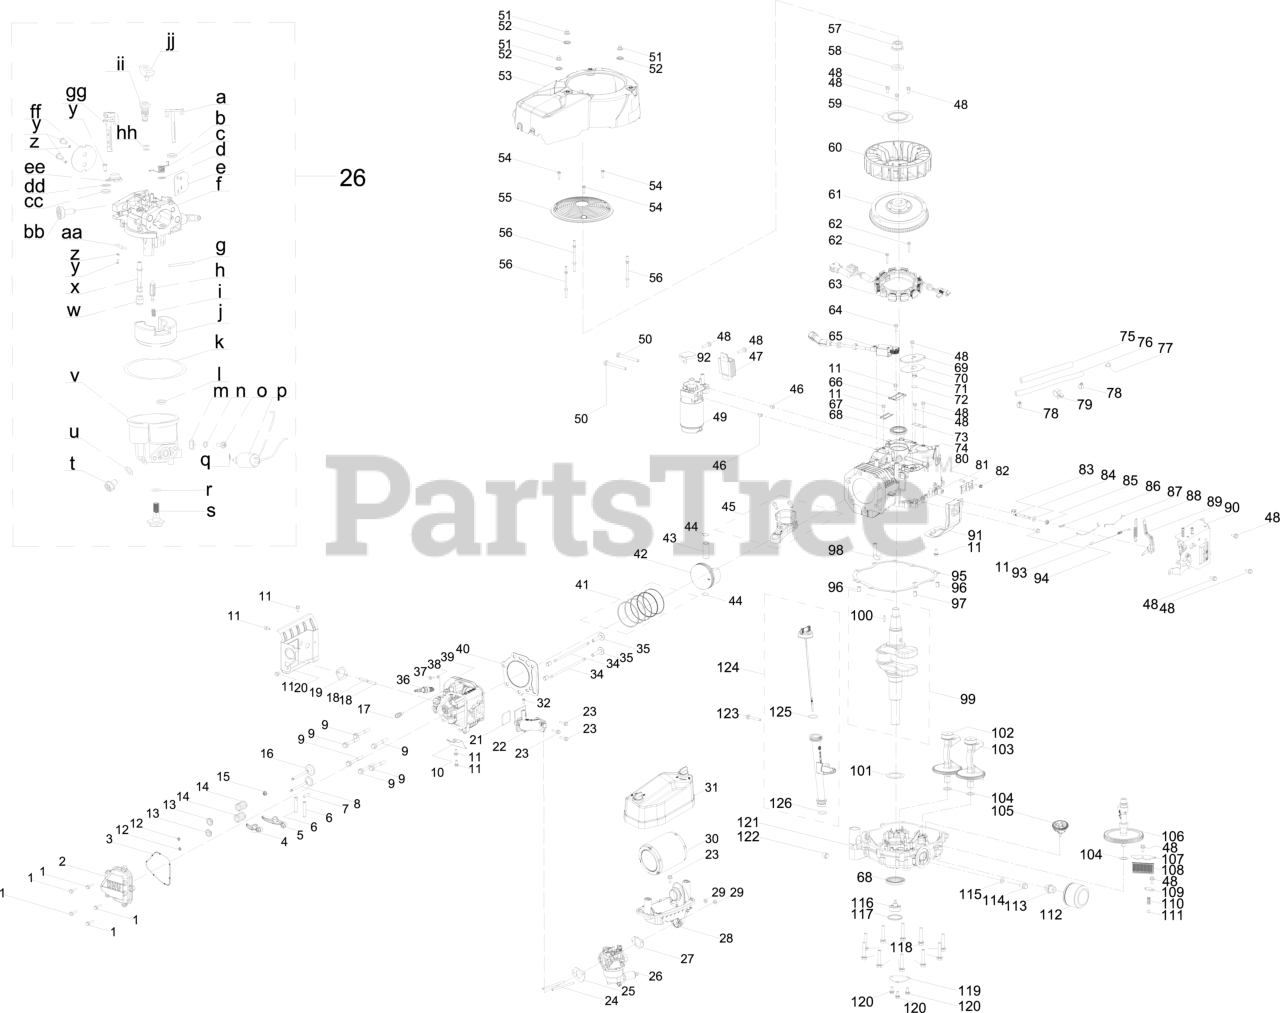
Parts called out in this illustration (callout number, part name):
1	BOLT M6-1 x 25 GR8.8
2	VALVE COVER
3	VALVE COVER GASKET
4	ROCKER ARM (INTAKE)
5	ROCKER ARM (EXHAUST)
6	ROCKER ARM SHAFT
7	CAMSHAFT PIN
8	EXHAUST VALVE
9	BOLT M10-1.25 x 70
11	BOLT M6-1 x 12 GR8.8
12	VALVE CAP
13	VALVE SPRING SEAT
14	VALVE SPRING
15	INTAKE VALVE SEAL
16	INTAKE VALVE
19	EXHAUST GASKET
20	SHROUD - LEFT SIDE
21	INTAKE PIPE RING
22	INTAKE PIPE
23	BOLT M6 x 22
24	STUD M6-1.00 x 92
25	INTAKE GASKET
27	AIR FLTER GASKET
28	INTAKE MANIFOLD
30	AIR FILTER W/PREFILTER
30	Cub Cadet AIR FILTER/PRE-FILTER
30	Genuine Factory Parts AIR FILTER
30	Troy-Bilt AIR FILTER (05066)
31	AIR FILTER COVER
32	SELF TAPPING SCREW 4.8 x 16
34	SINGLE PUSH ROD
36	SPARK PLUG (F6RTC/RN11YC/BPR6ES)
37	BOLT M5-.8 x 10
38	FLAT WASHER: 5.3 x 10 x 1
39	CYLINDER HEAD
40	CYLINDER HEAD GASKET
41	PISTON RING SET
43	PISTON PIN
44	PISTON PIN SNAP RING
45	CONNECTING ROD ASSEMBLY
48	BOLT M6-1 x 14 GR8.8
49	STARTER
50	BOLT M8-1.25 x 80
51	ACORN NUT
53	SHROUD
54	BOLT 5.5 x 25
55	DEBRIS SHIELD
57	NUT M20 x 1.5
58	WASHER 20.5 x 5 x 40
59	VANE PLATE
60	COOLING FAN
62	BOLT M5 x 28
63	CHARGING COIL
64	BOLT-M6-1 x 28 GR8.8
65	IGNITION COIL ASSEMBLY
66	BREATHER SCREEN
67	WIRE PLATE
68	OIL SEAL 38 x 58 x 8
69	BREATHER COVER
70	BREATHER COVER GASKET
71	BREATHER VALVE SPRING
72	BREATHER VALVE
75	PROTECTIVE SLEEVE TUBING
76	FUEL HOSE 6.3 x 12.5 x 250
78	HOSE CLAMP
79	FUEL LINE SUPPORT CLAMP
80	LIMIT HOSE
81	LIMIT PLATE
82	BOLT M5 x 18
83	GOVERNOR GEAR SHAFT
84	WASHER 8 x 0.8 x 16
85	GOVERNOR SEAL
86	GOVERNOR SHAFT CLIP
87	CHOKE LINKAGE
88	GOVERNOR SPRING
89	GOVERNOR LEVER
90	THROTTLE BRACKET ASSEMBLY
91	SHROUD - RIGHT
92	STARTER SHIELD BRACKET
93	THROTTLE LINKAGE
94	THROTTLE LINKAGE SPRING
95	CRANKCASE COVER GASKET
96	DOWEL PIN 9 X 14
97	DOWEL PIN
98	VENTING HOSE
99	CRANKSHAFT ASSEMBLY
100	WOODRUFF KEY
101	WASHER 38.3 x 54 x 1
102	BALANCE SHAFT (LH)
103	BALANCE SHAFT (RH)
104	WASHER 17.2 x 26 x 1
105	GOVERNOR GEAR ASSEMBLY
107	FILTER COVER
108	FILTER SCREEN
109	PRESSURE RELEASE COVER
110	PRESSURE RELEASE SPRING
111	OIL PUMP STEEL BALL
112	ENGINE OIL FILTER
112	Cub Cadet OIL FILTER
112	Genuine Factory Parts OIL FILTER
112	Troy-Bilt OIL FILTER
113	SCREW JOINT OIL FILTER ADAPTER
114	BOLT M8 x 15
115	OIL DRAIN PLUG WASHER
116	OIL PUMP ASSEMBLY
118	BOLT M8 x 45
119	OIL SEPARATOR
120	SCREW M6-1 x 16
121	CRANKCASE COVER
122	ENGINE PLUG 3/8 NPT
123	BOLT M6-1 x 45 CL5.8
124	DIPSTICK ASSEMBLY
